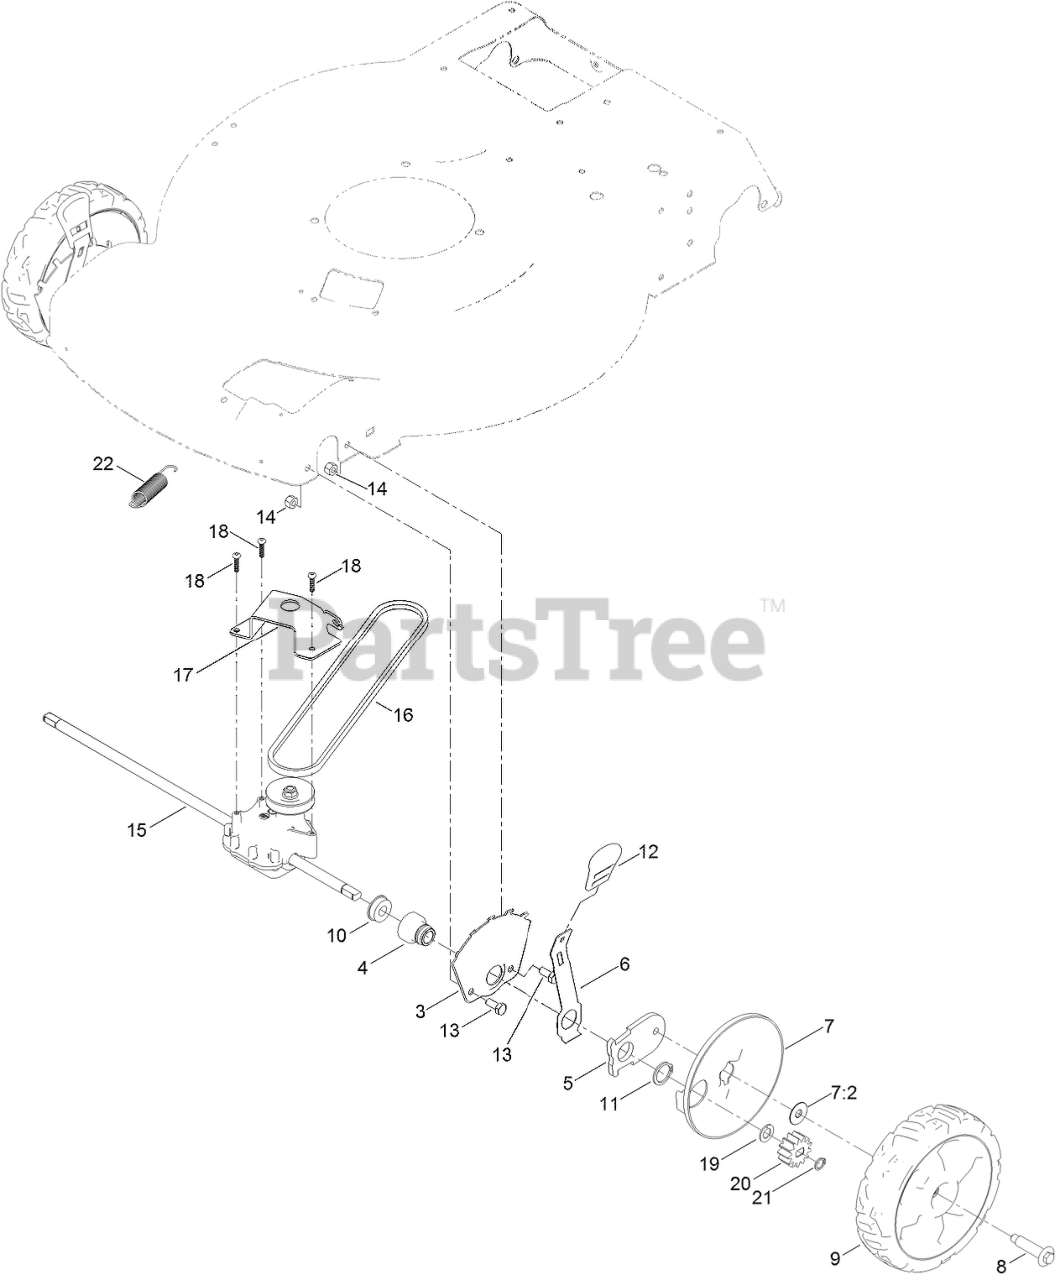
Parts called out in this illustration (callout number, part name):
3	PLATE-HOC, FRONT
4	RETAINER-BEARING, HOC
5	ARM-PIVOT, FRONT
6	ARM-SPRING
7	WHEEL COVER ASM
7:2	WASHER-STEPPED
8	BOLT-SHOULDER
9	WHEEL ASM, 8IN
10	BEARING-BALL
11	RING-RETAINING
12	KNOB-HOC
13	SCREW-HH
14	NUT-HEX
15	TRANSMISSION
16	V-BELT
17	BRACKET-TRANSMISSION
18	SCREW-PLASTITE
19	WASHER-THRUST
20	GEAR-PINION, 13T
21	RING-RETAINING
22	SPRING-EXTENSION
